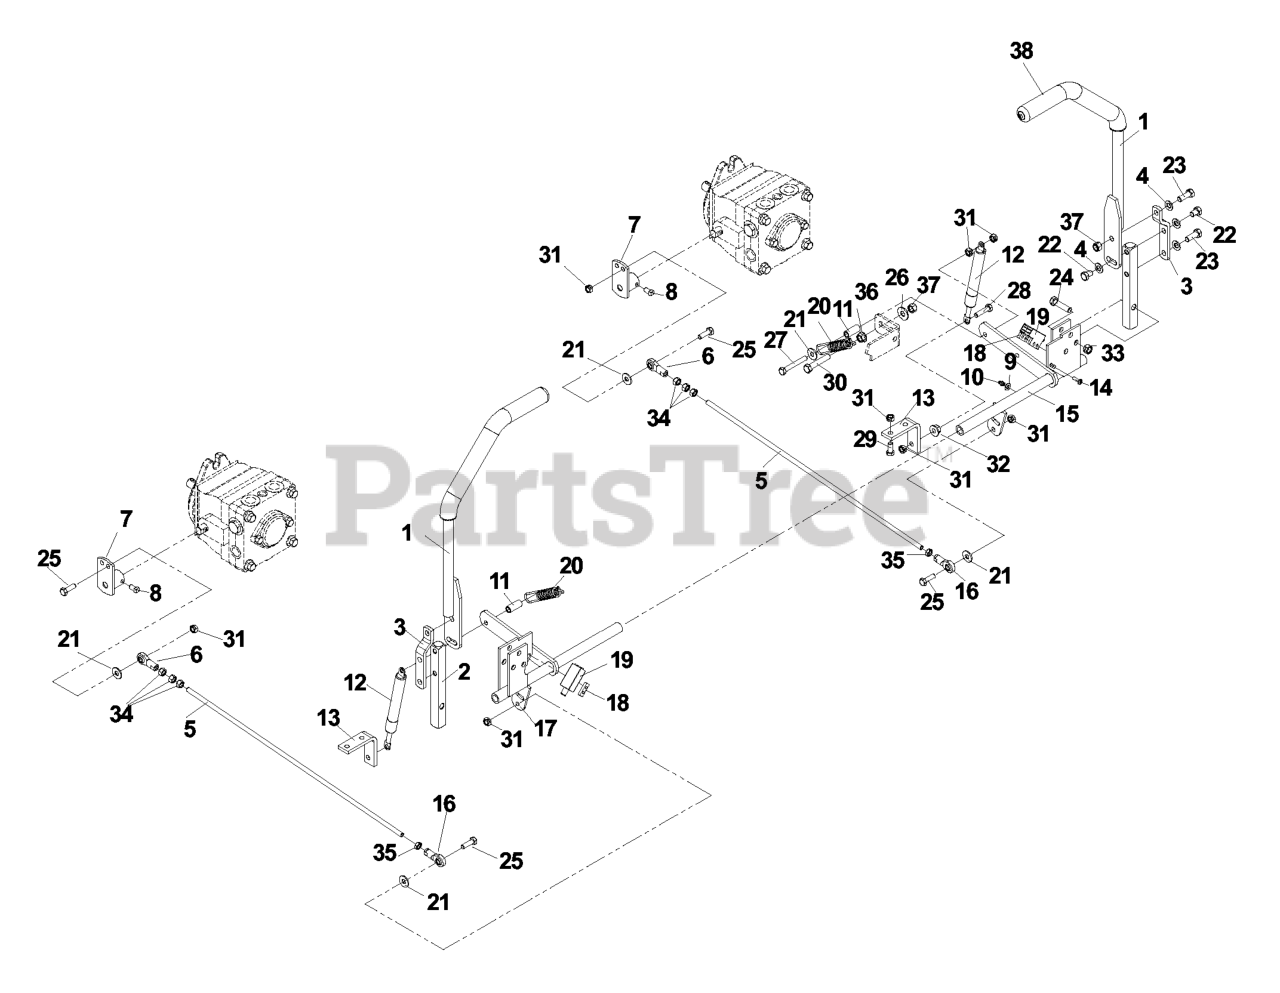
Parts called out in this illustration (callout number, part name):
1	CONTROL LEVER WELDMENT
2	CONTROL ARM
3	CONTROL LEVER EXT
4	WASHER, 3/8 DISC SPRING SPEC
5	PUMP LINKAGE BAR
6	BALL JOINT, RIGHT HANDED
7	PUMP LEVER
8	5/16C X 5/8 "V" POINT
10	ZERK
13	L BRACKET-PAINTED
14	SCREW #10-24 X 5/8
15	CONTROL WELDMENT LT
16	BALL JOINT, LEFT HANDED
17	CONTROL WELDMENT RT.
18	TAPPED PLATE
21	WASHER 5/16 FLAT
22	BOLT .375 X .5
23	HCS 3/8-16X1.GRD.5.ZD
24	HCS 3/8C X 1 1/2
25	HCS 5/16C X 1
26	WASHER 3/8 FLAT
27	TAP BOLT 5/16C X 2 1/4
28	HCS 5/16C X 1 1/4
29	HCS 5/16C X 3/4
30	HCS 3/8C X 2
31	NUT 5/16C CENTERLOCK
32	NUT 5/16C WHIZ
33	NUT 3/8C CENTERBLOCK
35	NUT 5/16F LEFTHAND
36	NUT 3/8C WHIZ
37	NUT 3/8-16 NYLOC
